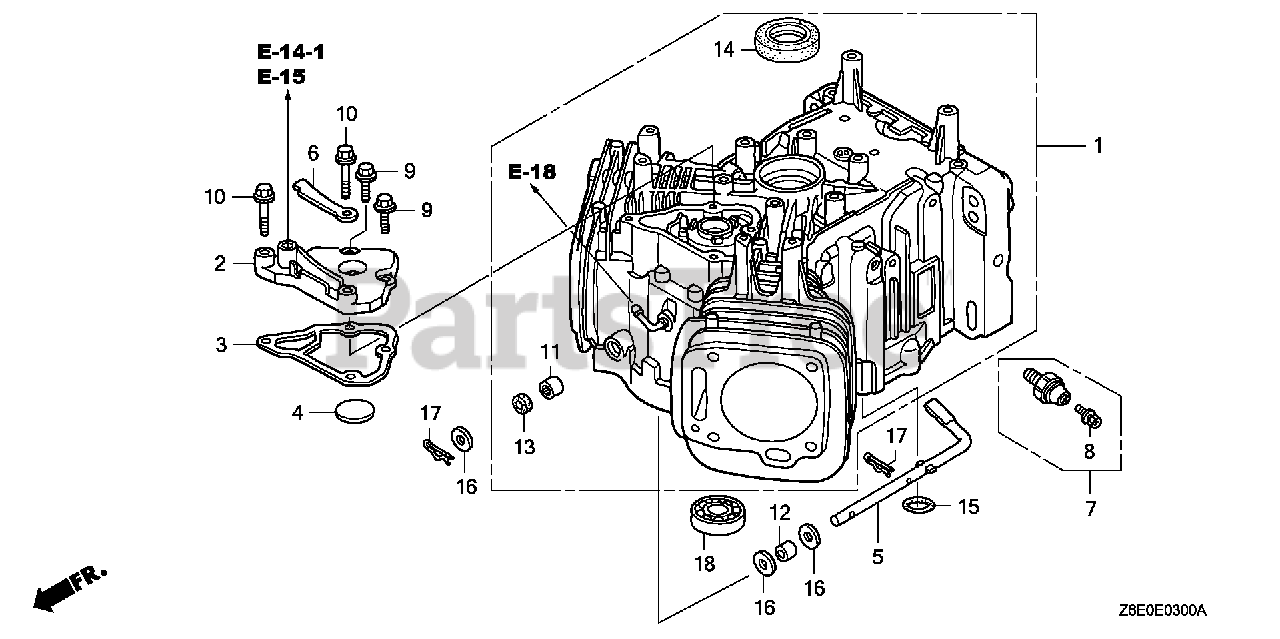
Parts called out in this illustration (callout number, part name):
1	CYLINDER ASSY.
2	COVER, BREATHER
3	GASKET, BREATHER COVER
4	VALVE, BREATHER
5	SHAFT, GOVERNOR ARM
6	CLAMP, WIRE
7	SWITCH ASSY., OIL PRESSURE
7	SWITCH, OIL PRESSURE
8	SCREW-WASHER (4X8)
9	BOLT, FLANGE (6X16) (CT200)
10	BOLT, FLANGE (6X32) (CT200)
11	BEARING, NEEDLE (8X12.7X11.1)
12	BEARING, NEEDLE (8X12X10)
13	OIL SEAL (8X14X5)
14	OIL SEAL (38X58X9)
15	O-RING (13X3.0)
16	WASHER, PLAIN (8MM)
17	PIN, LOCK (8MM)
18	BEARING, RADIAL BALL (6003)
